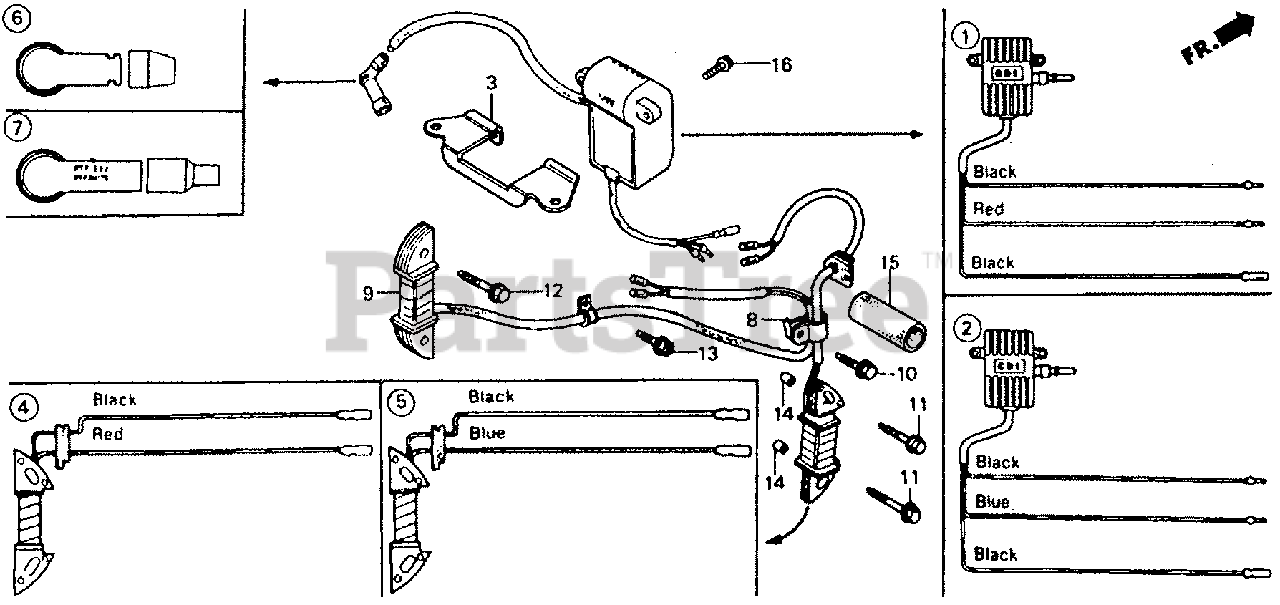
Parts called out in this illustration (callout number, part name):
1	MODULE, IGNITION CONTROL (CDI)
3	STAY, IGNITION CONTROL MODULE
4	COIL ASSY., EXCITER
6	TERMINAL ASSY., IGNITION
7	CAP ASSY., NOISE SUPPRESSOR
8	CLAMP, IGNITION WIRE
10	BOLT, FLANGE (6X12) (CT200)
11	BOLT, FLANGE (6X28)
14	PIN A, DOWEL (8X14)
15	TUBE, VINYL (22X27X60) (NOT AVAILABLE)
16	BOLT, FLANGE (6X12)
